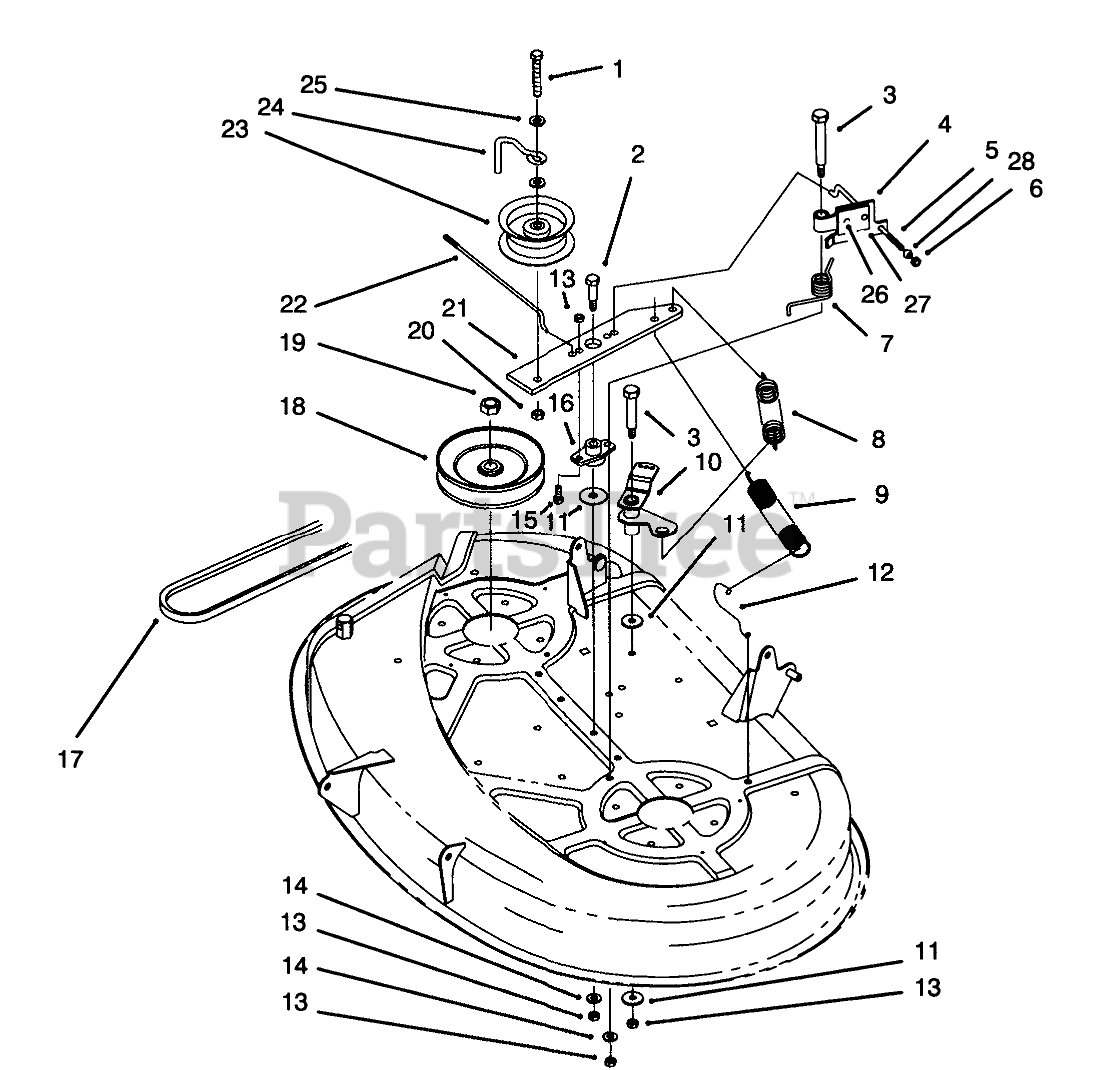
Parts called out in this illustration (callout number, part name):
1	SCREW-HH
2	SCREW-SHOULDER, HH
3	BOLT-SHOULDER
4	Brake-Deck (Incl. Ref. #26 & 27)
5	ROD-BRAKE, DECK LH
6	NUT-LOCK, NI
7	SPRING-TORSION
8	SPRING-DECK, ENGAGEMENT
9	SPRING-EXTENSION
10	Bellcrank
11	WASHER-FLAT
12	HOOK-RETURN, SPRING
13	NUT-LOCK, NI
14	WASHER-PLAIN
15	SCREW-HH
16	BUSHING-ARM, IDLER
17	BELT-V
18	PULLEY
19	NUT-HEX
20	NUT-LOCK, NI
21	Arm-Idler
22	ROD-BRAKE, DECK RH
23	PULLEY-IDLER, FLAT
24	GUIDE-IDLER, BELT
25	WASHER-FLAT
26	RIVET-BLIND
27	PAD-BRAKE
28	BALL-SWIVEL, STOP
